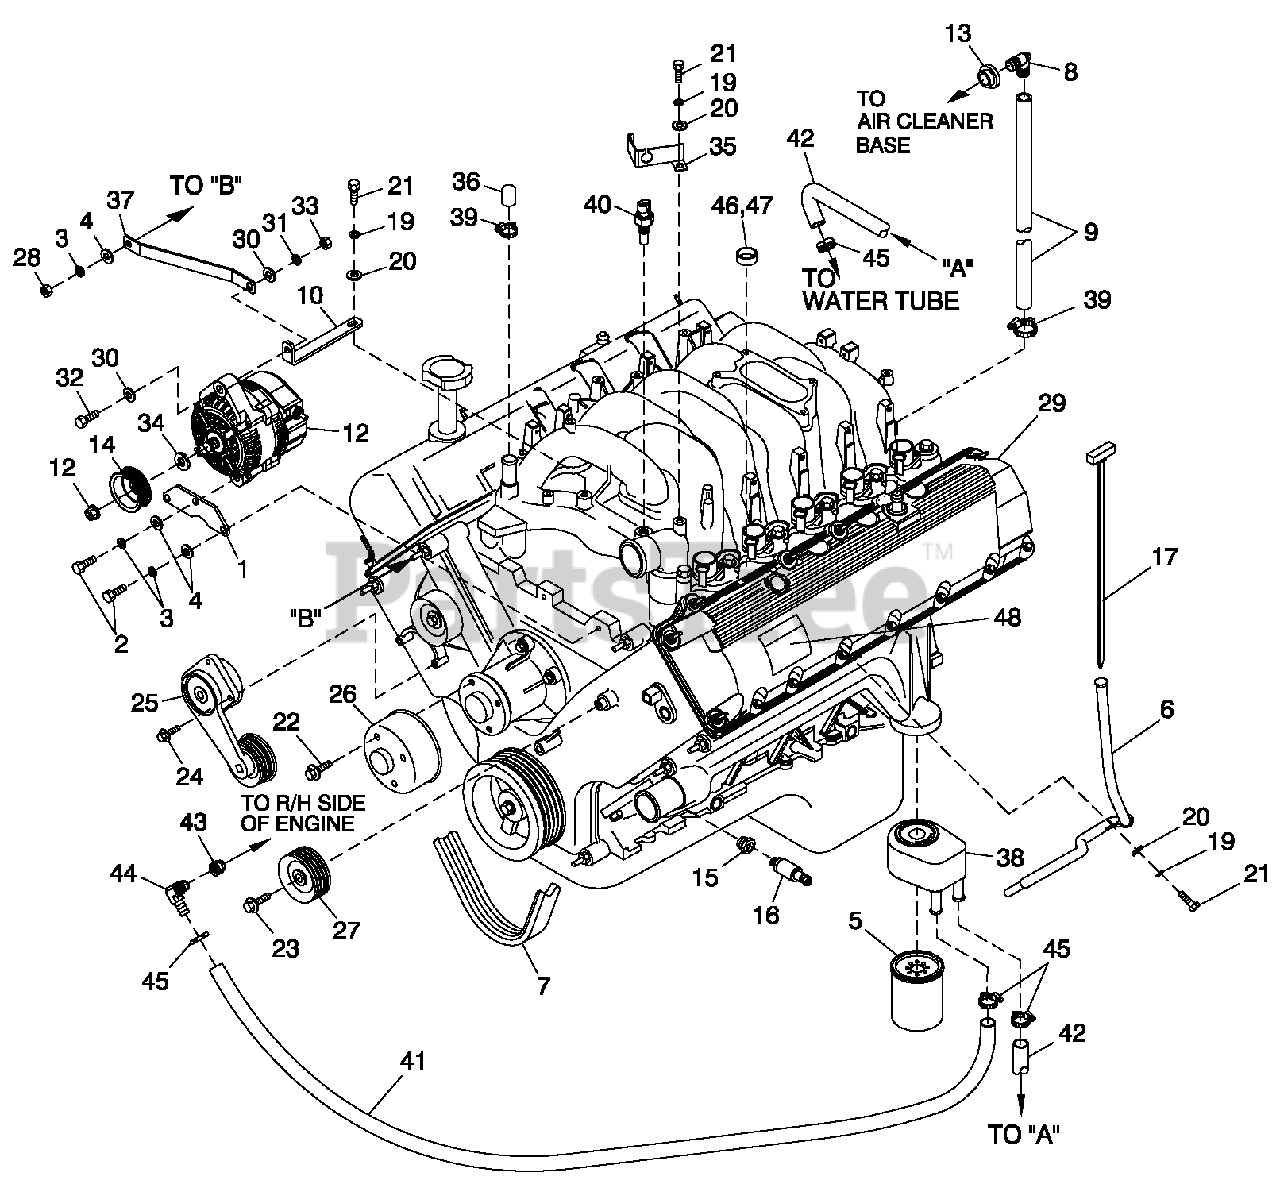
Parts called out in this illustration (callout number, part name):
1	BRACKET,D.C. ALTERNATOR LOWER
2	SCREW HHC M8-1.25X 20 G8.8
3	WASHER LOCK M8-5/16
4	WASHER FLAT 5/16-M8 ZINC
5	OIL FILTER, FORD V-10 ENGINE
6	DIPSTICK TUBE, FORD 6.8L
7	BELT SERPENTINE (65.0" LG) (1800 RPM)
8	BARBED EL 90 3/4 PLASTIC
9	HOSE 3/4 ID SAE-30R2 (16.75+LG)
10	BRACKET DC ALTERNATOR UPPER
12	ALTERNATOR DC W/OUT PULLEY
13	GROMMET
14	PULLEY 80 OD DC ALTERNATOR (1800 RPM)
15	BUSHING REDUCER 3/8 TO 1/8 GAL
16	SENDER OIL PRESSURE 1/8" NPT
17	DIPSTICK 6.8L FORD
19	WASHER LOCK M6-1/4
20	WASHER FLAT 1/4 ZINC
21	SCREW HHC M6-1.0X 20 G8.8
22	BOLT WATER PUMP PULLEY
23	BOLT GROOVED IDLER PULLEY
24	BOLT BELT TENSIONER
25	TENSIONER ENG. AUTOMATIC BELT
26	PULLEY WATER PUMP FORD (1800RPM UNITS)
27	PULLEY GROOVED ENGINE IDLER
28	NUTHEXM8-1.25 G8YEL CHR
29	ENGINE G6.8L G3V-10
30	WASHER FLAT 3/8-M10 ZINC
31	WASHER LOCK M10
32	SCREW HHC M10-1.5 X 45 G8.8 FT
33	NUTHEXM10-1.5 G8YEL CHR
34	SPACER DC ALTERNATOR PULLEY
35	BRACKET SIGNAL CONDITIONER
36	CAP RUBBER
37	BRACKET DC ALT STABILIZER
38	OIL COOLER FORD (150KW 3600RPM)
39	CLAMP HOSE #10 .56-1.06
40	TEMPERATURE SENDER DELPHI
41	HOSE OIL COOLER PREFORMED 3/4 (150KW 3600RPM)
42	HOSE OIL COOLER (150KW 3600RPM)
43	ADAPTOR 1/2" NPT - 3/8" NPT (150KW 3600RPM)
44	BARBED EL 90 1/2 NPT X 3/4 HOSE (150KW 3600RPM)
45	CLAMP HOSE #10 .56-1.06 (150KW 3600RPM)
46	PLUG EXPANSION 14 OD
47	ADHESIVE LOCTITE 620
48	DECAL EMISSION CTRL INFO 6.8L
